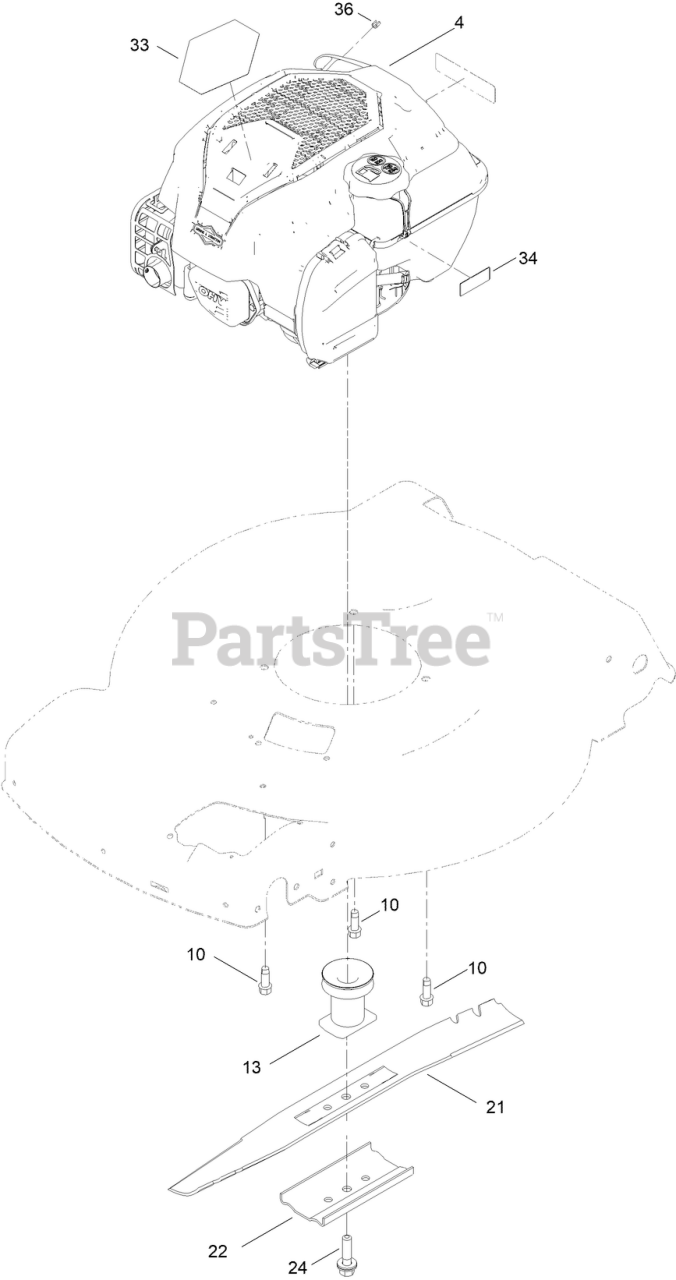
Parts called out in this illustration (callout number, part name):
10	SCREW-TAPTITE
13	DRIVER-BLADE
22	SUPPORT-BLADE
24	BOLT-BLADE
33	DECAL - BRIGGS 675 EXI SS
34	DECAL-LEVEL, FUEL
36	STOP-ROPE
